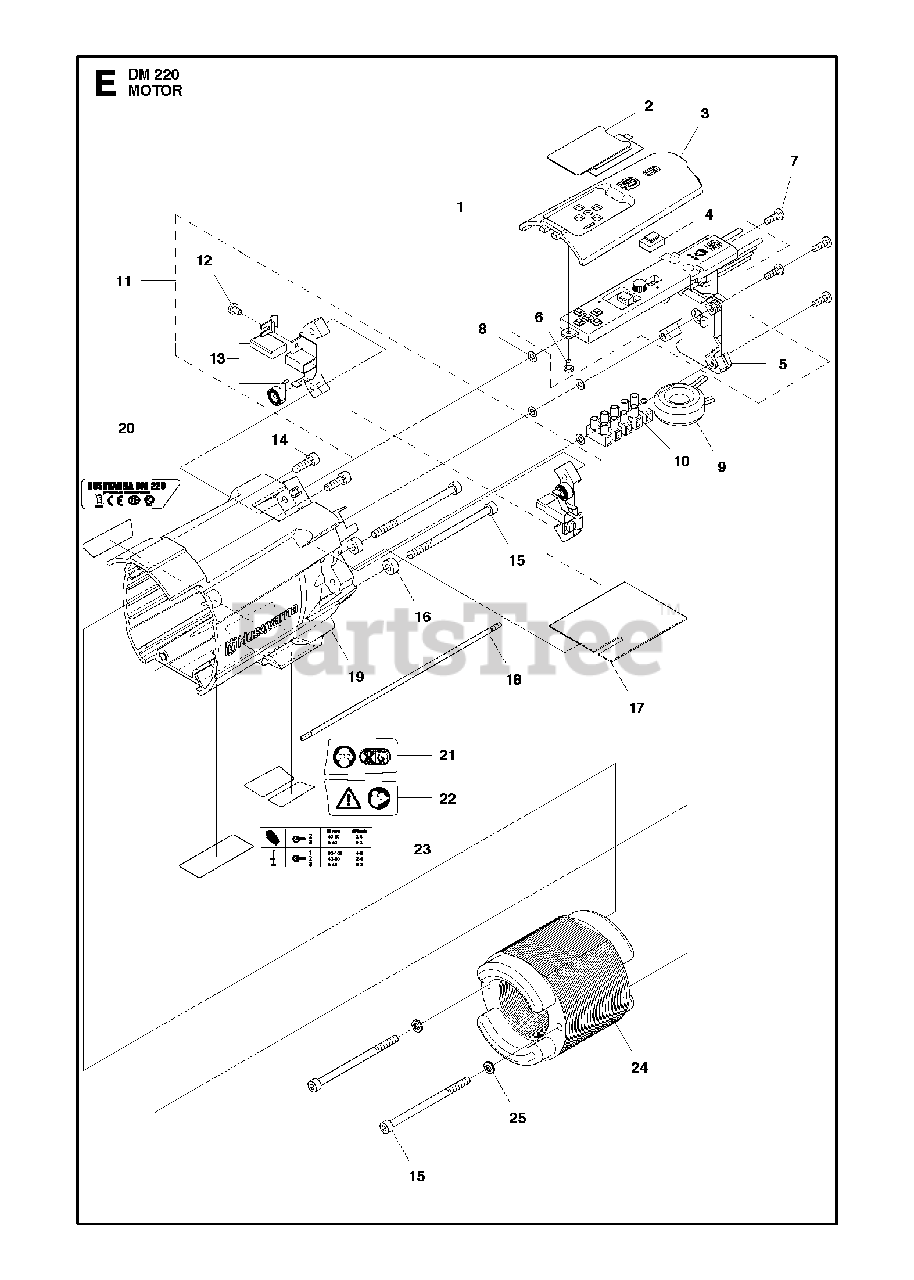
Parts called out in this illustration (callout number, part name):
1	CIRCUIT BOARD ASSY230V
5	CIRCUIT BOARD ASSY120V
5	CIRCUIT BOARD ASSY230V
8	SPRING WASHER
12	SCREW SLPANM
13	BRUSH KITContains two brushes and two springs
15	SCREW IHSCM
